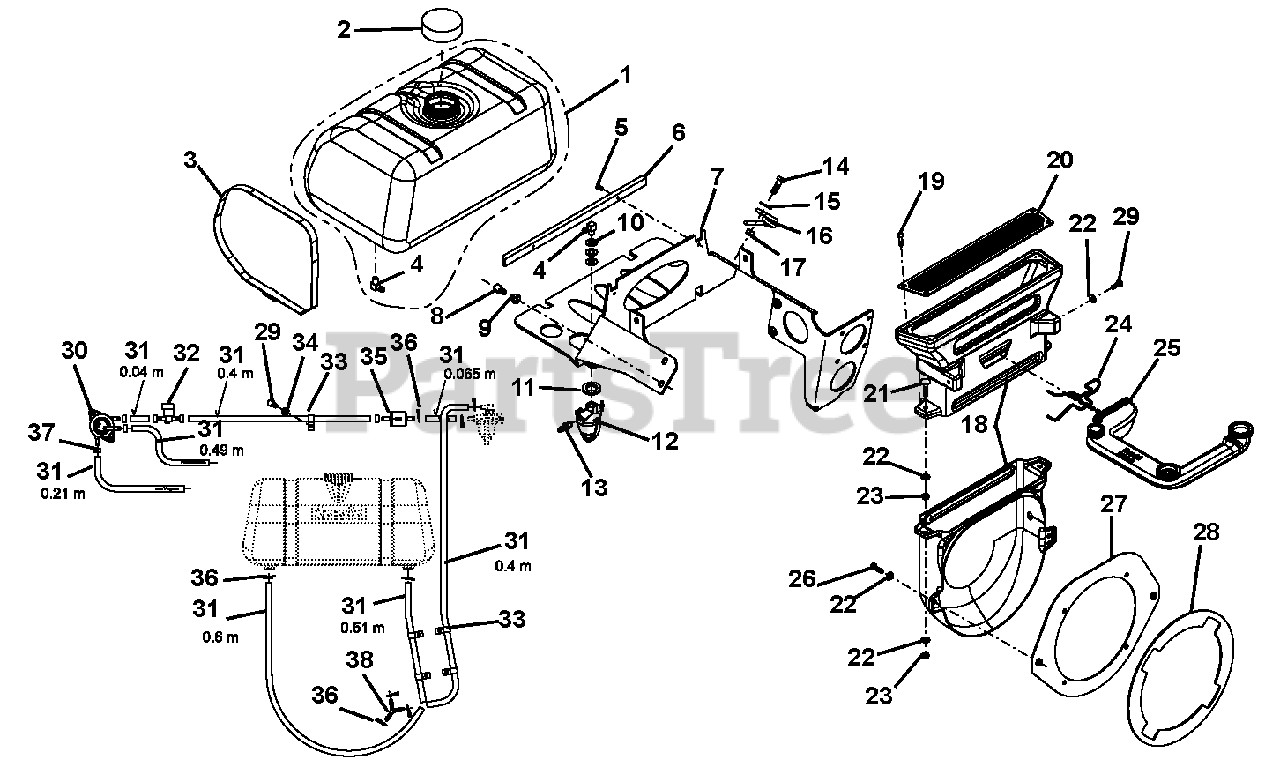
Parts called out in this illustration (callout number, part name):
1	Fuel Tank, INKL. (Includes item 4)
2	Cap, Fuel
4	Connector
5	Countersunk Bolt, D7991 Metric 5X
6	Base, Plastic
7	Fuel Gauge
8	Bolt, Hex D933 M8 x 20
9	Washer, M8
10	Bell Washer, D2093B 20 x 10,2
11	Washer, D1440 20 x 32 x 4
12	Gasoline Filter
13	Connector, 495.194
14	Hex Bolt, D933 Metric 8 x 25
15	Washer, Metric 8
17	Nut, Lock, D985 Metric 8
18	Channel Assembly, 20 Pro Steer
19	Oval Head Screw, D7981C 6,3
21	Screw, BN 289 M6 x 30
22	Washer, M6
23	Nut, Lock, D985 M6
25	Pipe, 228.6 x 253.31 x 49.5
26	Hex Bolt, D933 Metric 6 x 20
28	Spacer Plate
29	Hex Bolt, D933 Metric 6 x 16
30	Fuel, Pump, 808.856
32	Fuel Cock, Gasoline Shut-Off
33	Mounting Clip, 12 x 1
34	Washer, M6
35	Gasoline Filter, 691035
36	Hose, Clamp
37	Clamp, 93.053
38	Fitting, Y
